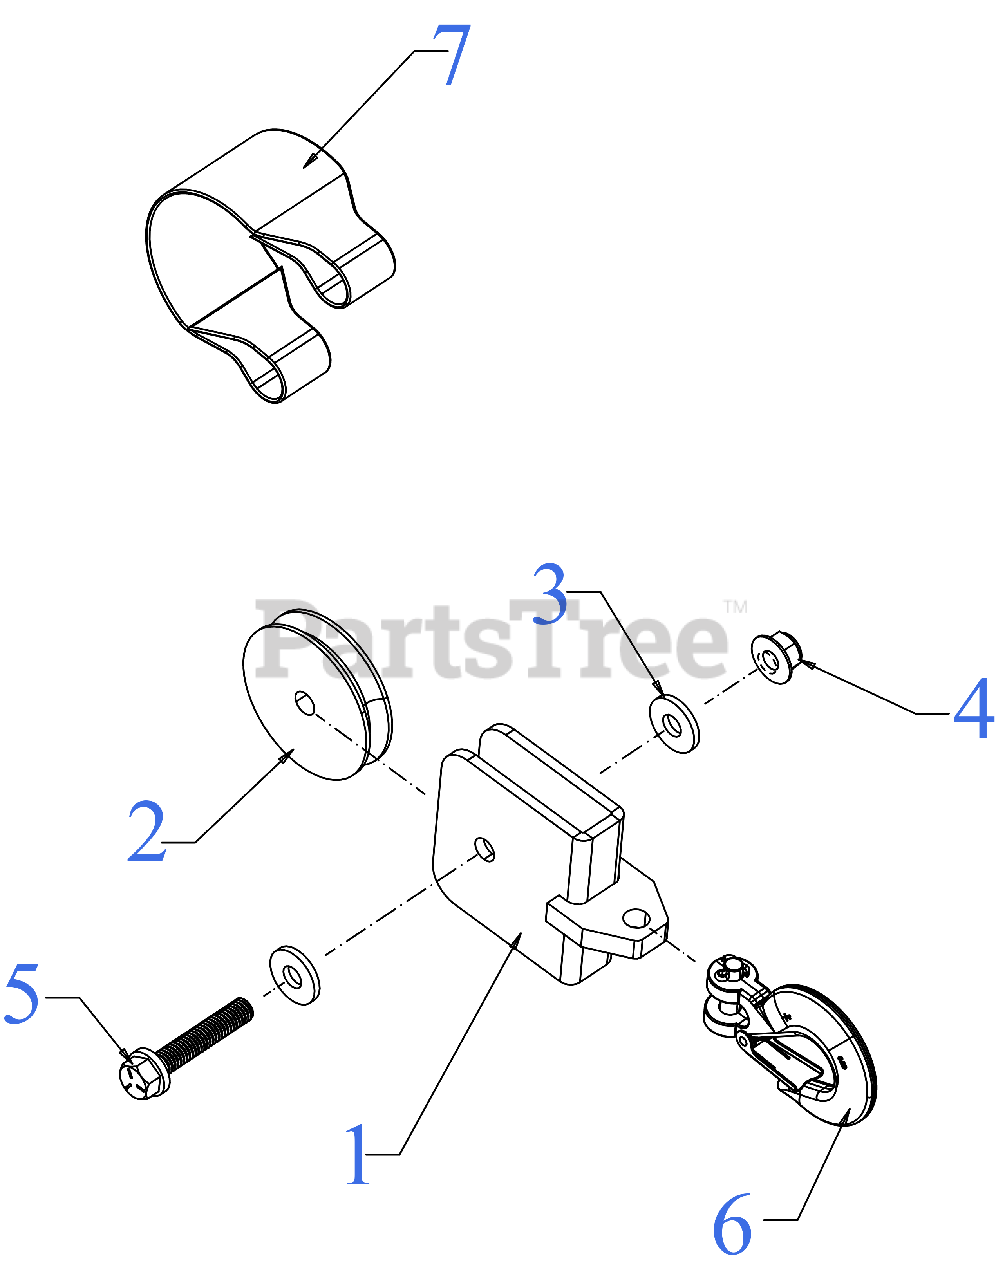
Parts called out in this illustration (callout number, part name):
1	PULLEY BRACKET
2	ALUMINUM 2" ROLLER
5	SCREW 3/8-16 x 2.00 GR5
6	CLEVIS PIN HOOK
7	CABLE STRAP
